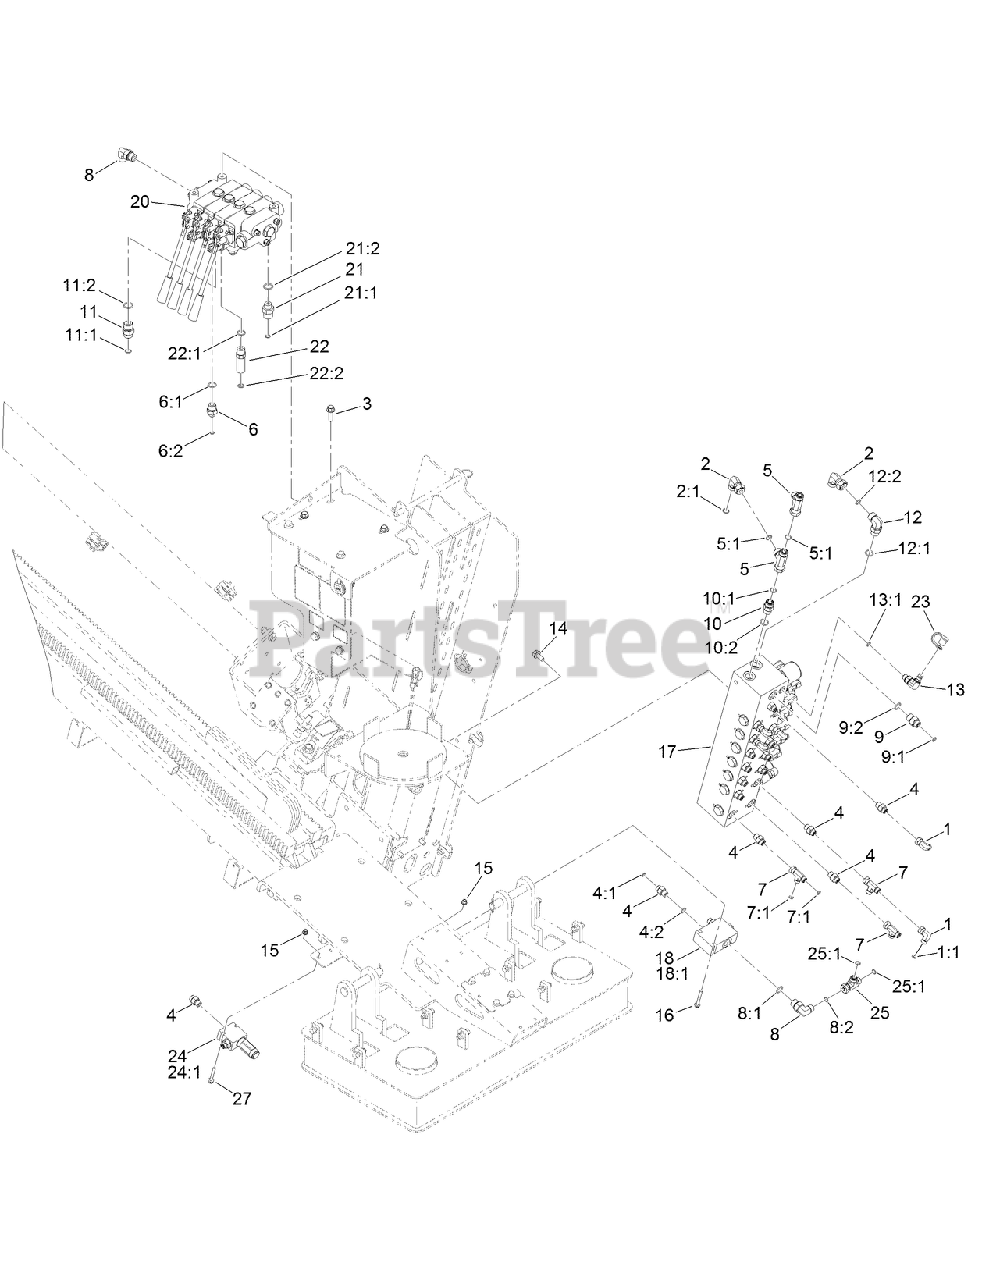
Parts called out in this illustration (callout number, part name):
1	FITTING-ADAPTOR
1:1	O-RING
2	FITTING-HYD
2:1	O-RING
3	SCREW-HHF
4	FITTING-STRAIGHT
4:1	O-RING
4:2	O-RING
5	FITTING-HYD, TEE
5:1	O-RING
6	FITTING-STR
6:1	O-RING
6:2	O-RING
7	FITTING-HYD
7:1	O-Ring
8	FITTING-HYD, 90 DEG
8:1	O-RING
8:2	O-RING
9	FITTING-STRAIGHT
9:1	O-RING
9:2	O-RING
10	FITTING-STRAIGHT
10:1	O-RING
10:2	O-RING
11	FITTING-STRAIGHT
11:1	O-RING
11:2	O-RING
12	FITTING-ELBOW-90 DEG
12:1	O-RING
12:2	O-RING
13	FITTING-ELBOW, 90 DEG
13:1	O-RING
14	SCREW-HHF
15	NUT-FLANGE, NI
16	SCREW-HHF
17	9 SECTION HYD VALVE ASM
18	HYD FLOW DIVIDER VALVE ASM
20	4 SPOOL HYD VALVE ASM
21	FITTING-HYD, STRAIGHT
21:1	O-RING
21:2	O-RING
22	FITTING-STR
22:1	O-RING
22:2	O-RING
23	CAP-DUST
24	VALVE-RELIEF
24:1	SEAL KIT
25	FITTING-TEE, SWIVEL NUT
25:1	O-RING
27	SCREW-HHF
